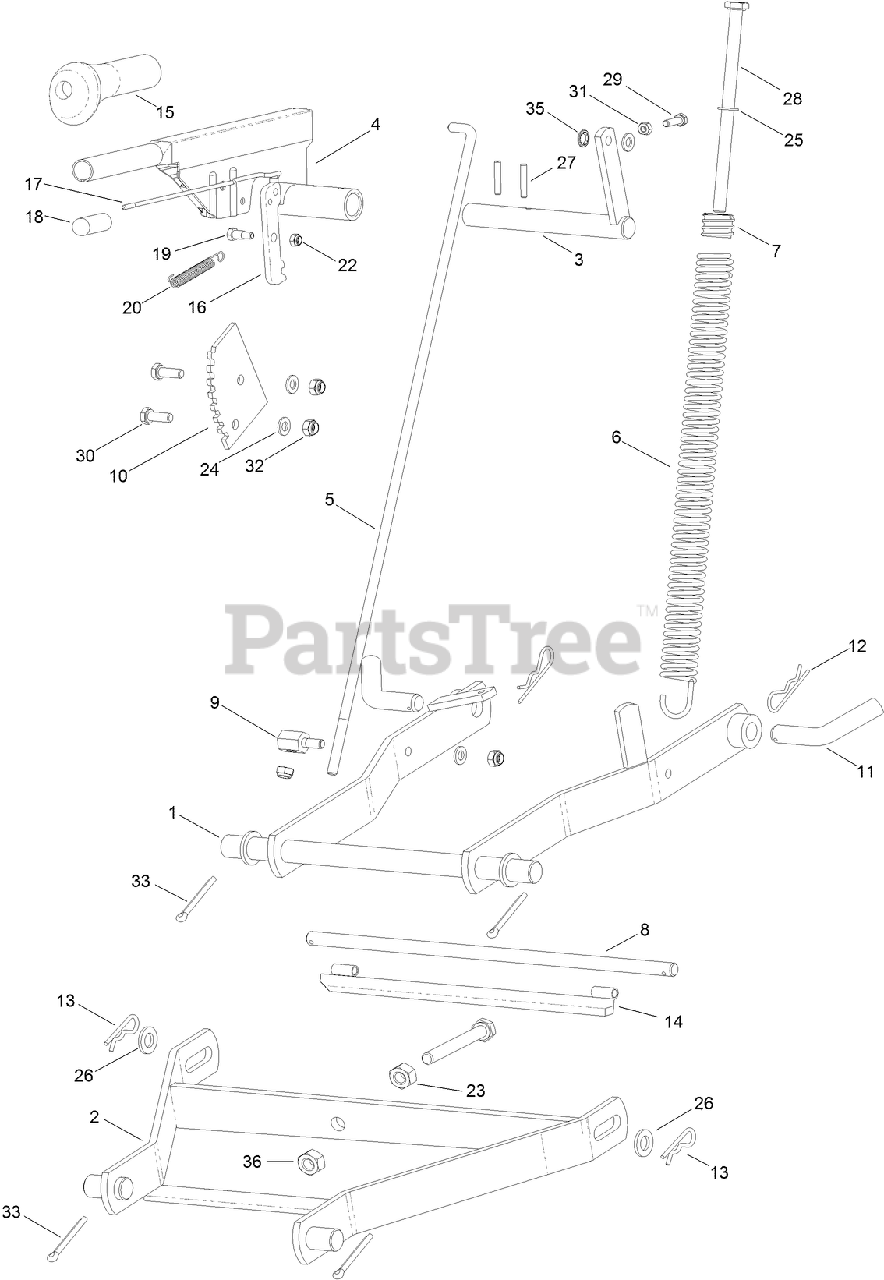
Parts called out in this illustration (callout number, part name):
1	SUSPENSION-DECK, MOWER
2	SUSPENSION-MOWER DECK, FRONT
3	SHAFT-ADJUSTMENT, HEIGHT
4	LEVER-ARM, HEIGHT ADJUST
5	ROD-ADJUSTMENT, HEIGHT
6	SPRING
7	NUT-SPRING
9	TRUNNION
10	SEGMENT-GEAR
11	PIN-BENT
12	PIN-HAIR
13	PIN-HAIR
14	HOLDER-FRONT
15	GRIP-HANDLE
16	RATCHET-PLATE, PIVOT
17	ROD-CONNECTION
18	BUTTON-PLUNGER
19	SCREW-LEVER
20	SPRING
22	NUT-LOCK
23	NUT-HEX
24	WASHER-PLAIN
25	WASHER-FLAT
26	WASHER-FLAT
27	PIN-SPRING
28	SCREW M10X180
29	SCREW-HH
30	SCREW-HH
31	NUT-HEX
32	NUT-LOCK, NI
33	PIN-COTTER
35	WASHER
36	NUT-LOCK, HEX NI
